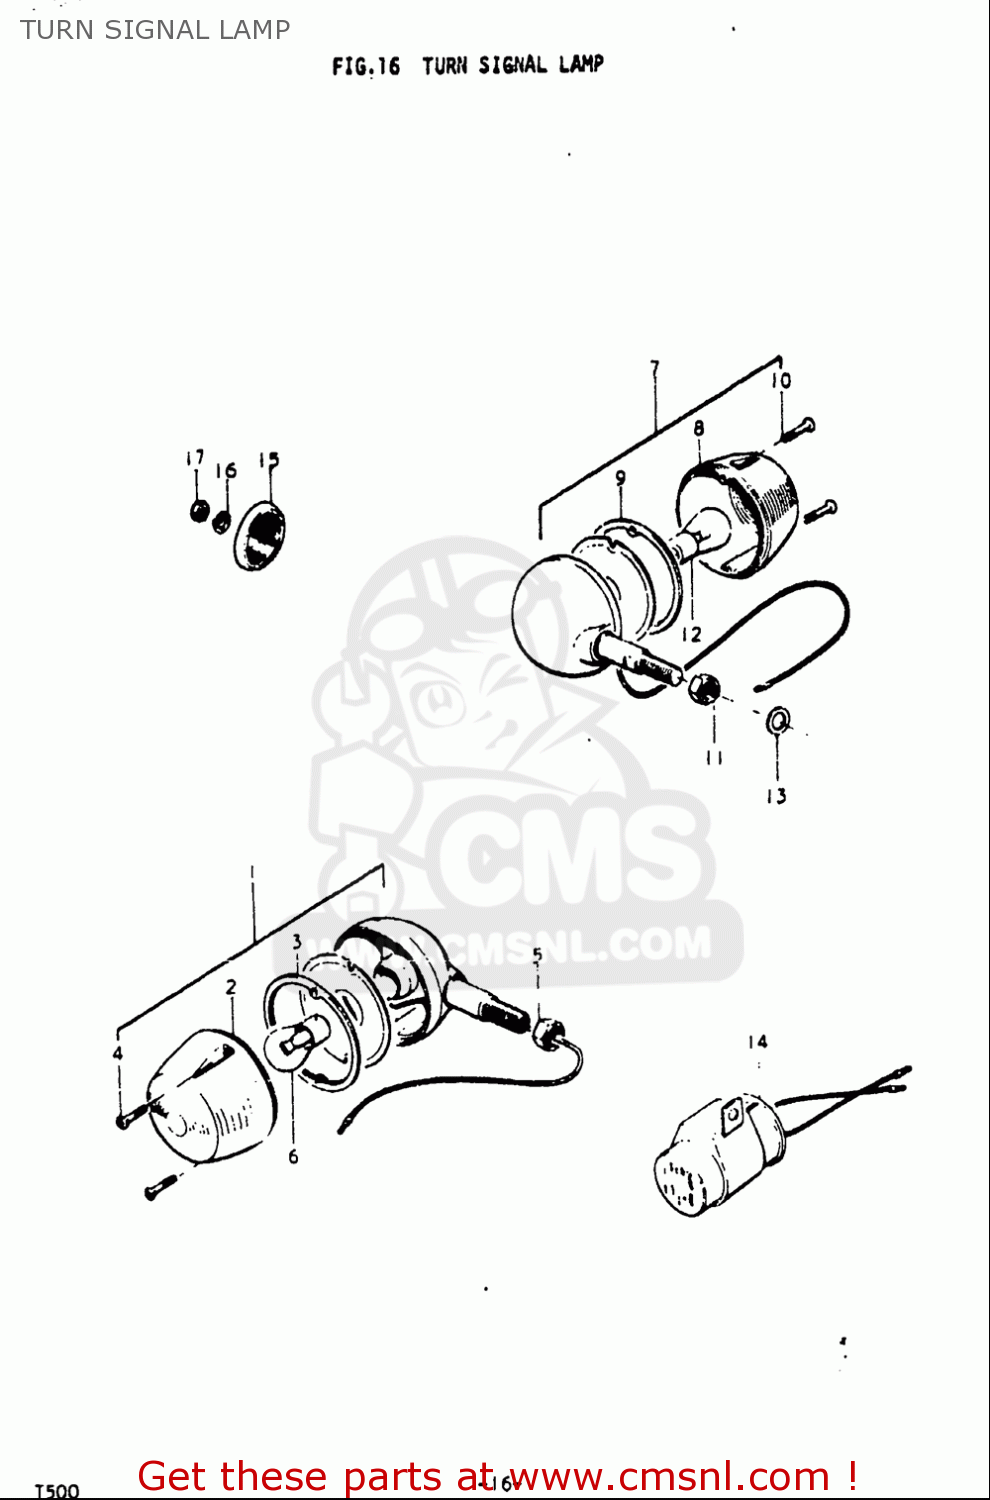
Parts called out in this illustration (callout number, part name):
1	LAMP ASSY,FR TURN SIGNAL
2	LENS,TURNSIGNAL
3	GASKET,TURNSIGNAL LENS (NAS)
4	SCREW
5	NUT
6	BULB(12V23W,STANLEY,A4577A)
7	LAMP ASSY,RR TURNSIGNAL
8	LENS,TURNSIGNAL
9	GASKET,TURNSIGNAL LENS (NAS)
10	SCREW
11	NUT
12	BULB(12V23W,STANLEY,A4577A)
13	WASHER
14	RELAY,TURN SIGNAL
16	WASHER,LOCK
17	NUT
